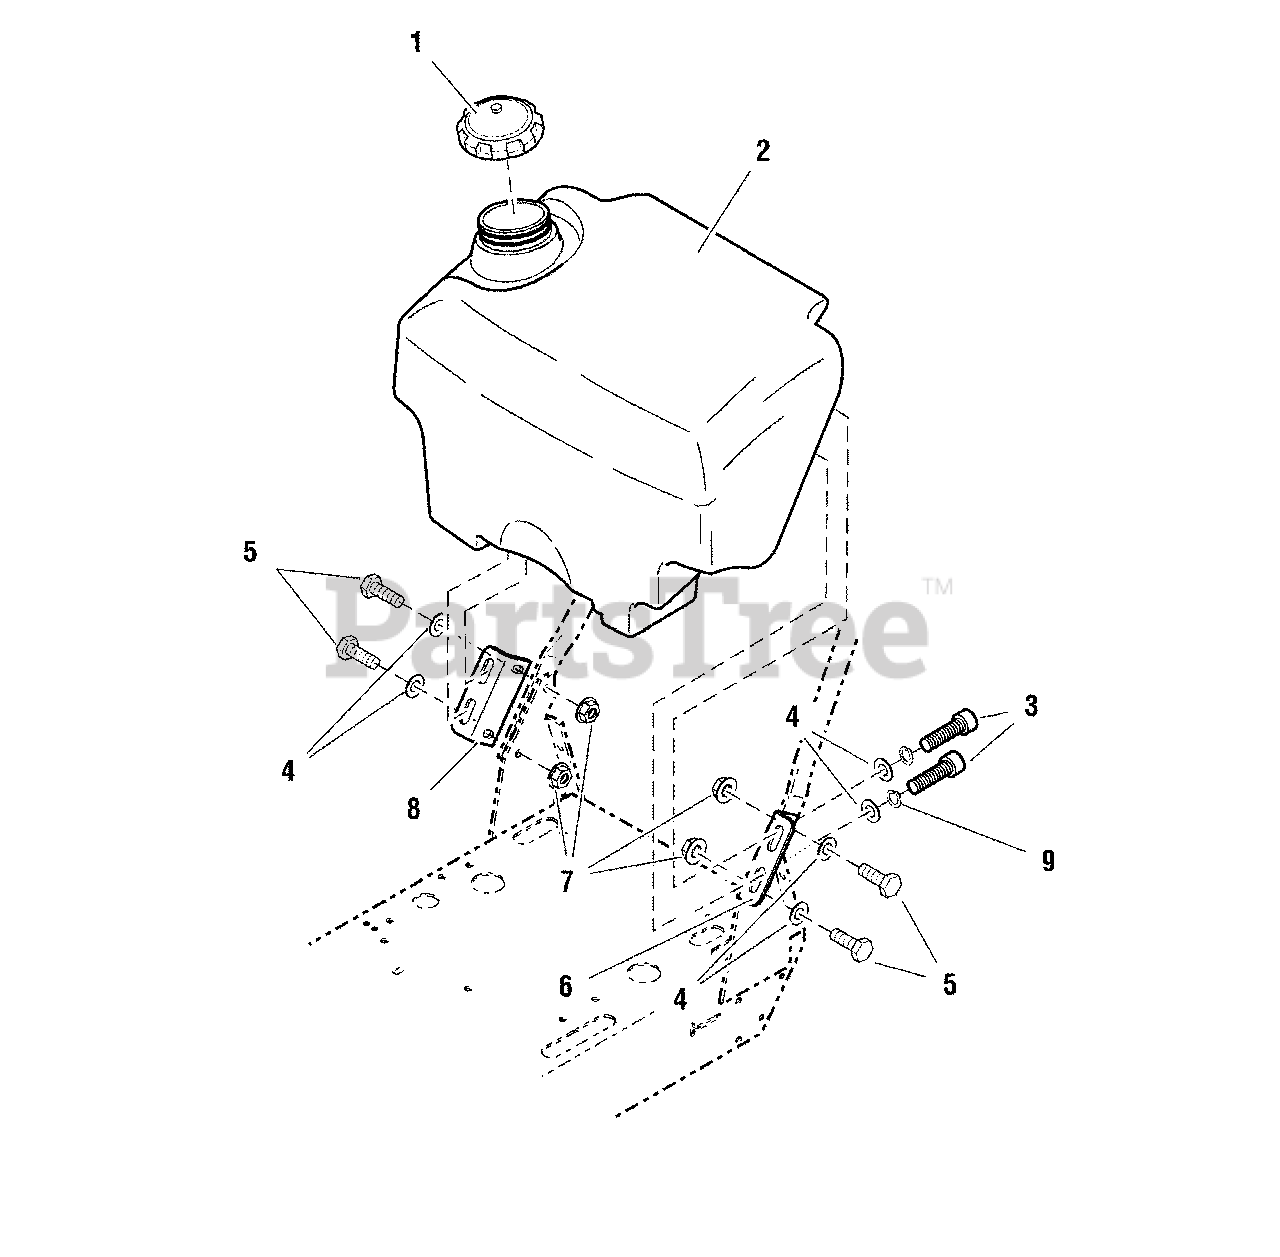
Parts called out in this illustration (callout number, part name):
1	FUEL CAP
3	BOLT, 3/8-16 X 3/4", ALLEN BUTTON
4	WASHER, 3/8
5	CAPSCREW, Hex Head, 3/8-16 x 1-1/4
6	FUEL TANK MOUNT - LH
7	NUT, 3/8-16 HEX NYLOCK FLANGE
8	FUEL TANK MOUNT - RH
9	WASHER, 5/16 LOCK YZ
